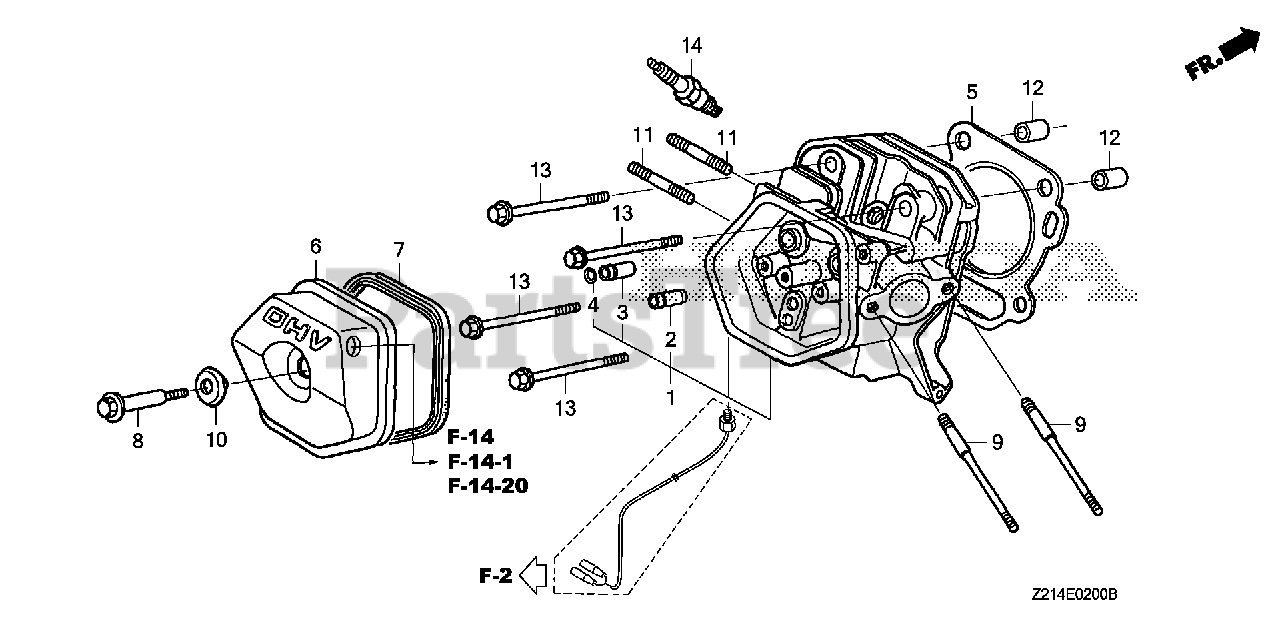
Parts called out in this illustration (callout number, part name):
1	CYLINDER HEAD
2	GUIDE, VALVE (OS)
3	GUIDE, EX. VALVE (OS)
4	CLIP, VALVE GUIDE
5	GASKET, CYLINDER HEAD
6	COVER, HEAD
7	GASKET, CYLINDER HEAD COVER
8	BOLT, HEAD COVER
9	BOLT, STUD (8X115)
10	WASHER, HEAD COVER
11	BOLT 2, STUD (8X32)
12	PIN A, DOWEL (12X20)
13	BOLT, FLANGE (10X80)
14	SPARK PLUG (BPR5ES) (NGK)
